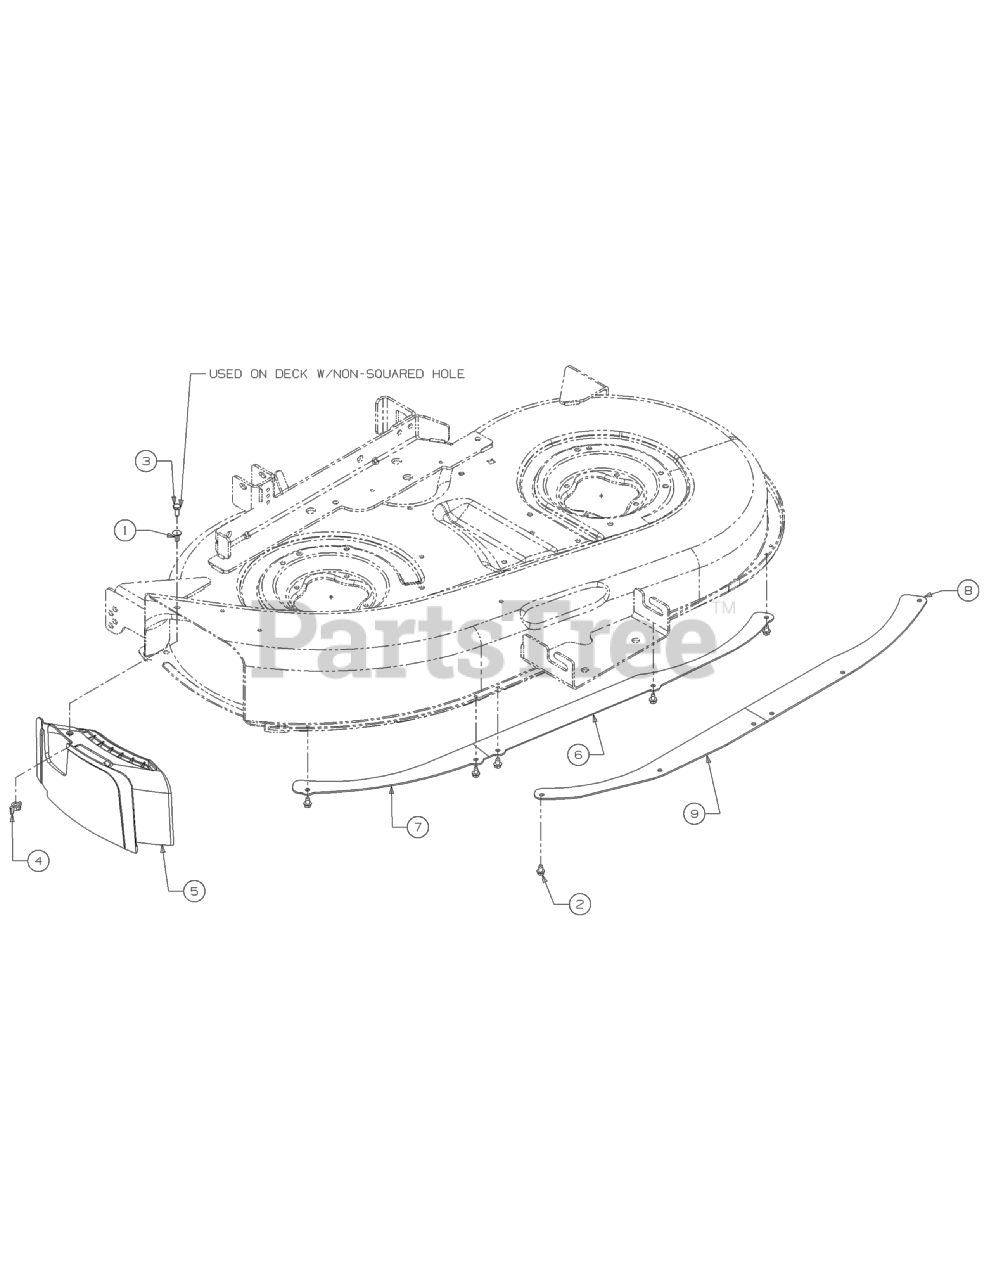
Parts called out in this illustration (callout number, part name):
1	1/4-20 x .6 Carriage Screw
2	1/4-20 x .5 Self-tapping Screws
3	1/4-20 x .6 Hex Screw
4	1/4-20 Plastic Wing Nut
5	Mulch Plug
